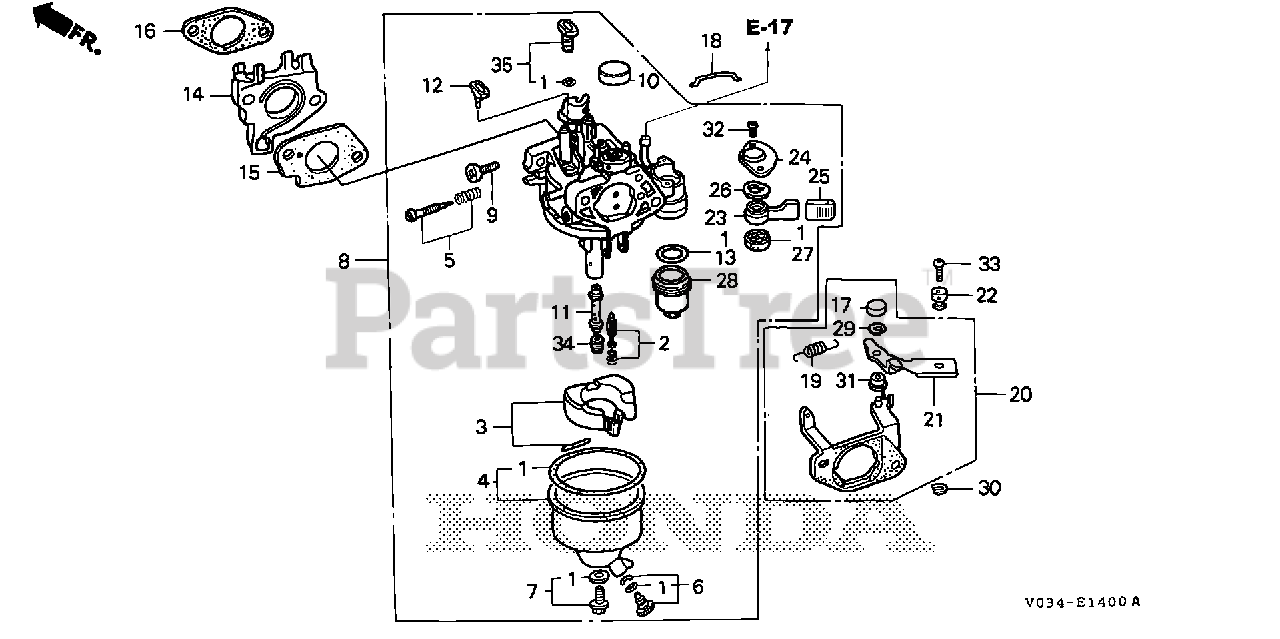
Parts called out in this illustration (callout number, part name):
1	GASKET SET
2	VALVE SET, FLOAT
4	CHAMBER SET, FLOAT
5	SCREW SET, PILOT
6	SCREW SET, DRAIN
7	SCREW SET
8	CARBURETOR ASSY. (BE80E A)
9	SCREW, THROTTLE STOP
10	CAP, CHOKE DUST
11	NOZZLE, MAIN
12	COLLAR, SETTING
13	GASKET, FUEL STRAINER CUP
14	INSULATOR, CARBURETOR
15	GASKET, CARBURETOR
16	GASKET, INSULATOR
17	CAP, CHOKE LEVER
18	ROD, CHOKE
19	SPRING, THROTTLE RETURN
20	STAY ASSY., CHOKE CONTROL (REMOTE)
21	LEVER, CHOKE
22	HOLDER, WIRE
23	LEVER, PETCOCK
24	PLATE, LEVER SETTING
25	CAP, LEVER
26	SPRING, PETCOCK LEVER
27	GASKET, PETCOCK
28	CUP, FUEL STRAINER
29	E-RING (4MM)
30	CIRCLIP (5MM)
31	BUSH, CHOKE LEVER
32	SCREW, PAN (3X6)
33	SCREW, PAN (4X6)
34	JET, MAIN (#95)
34	JET, MAIN (#98)
34	JET, MAIN (#92)
35	JET SET, PILOT (#35)
